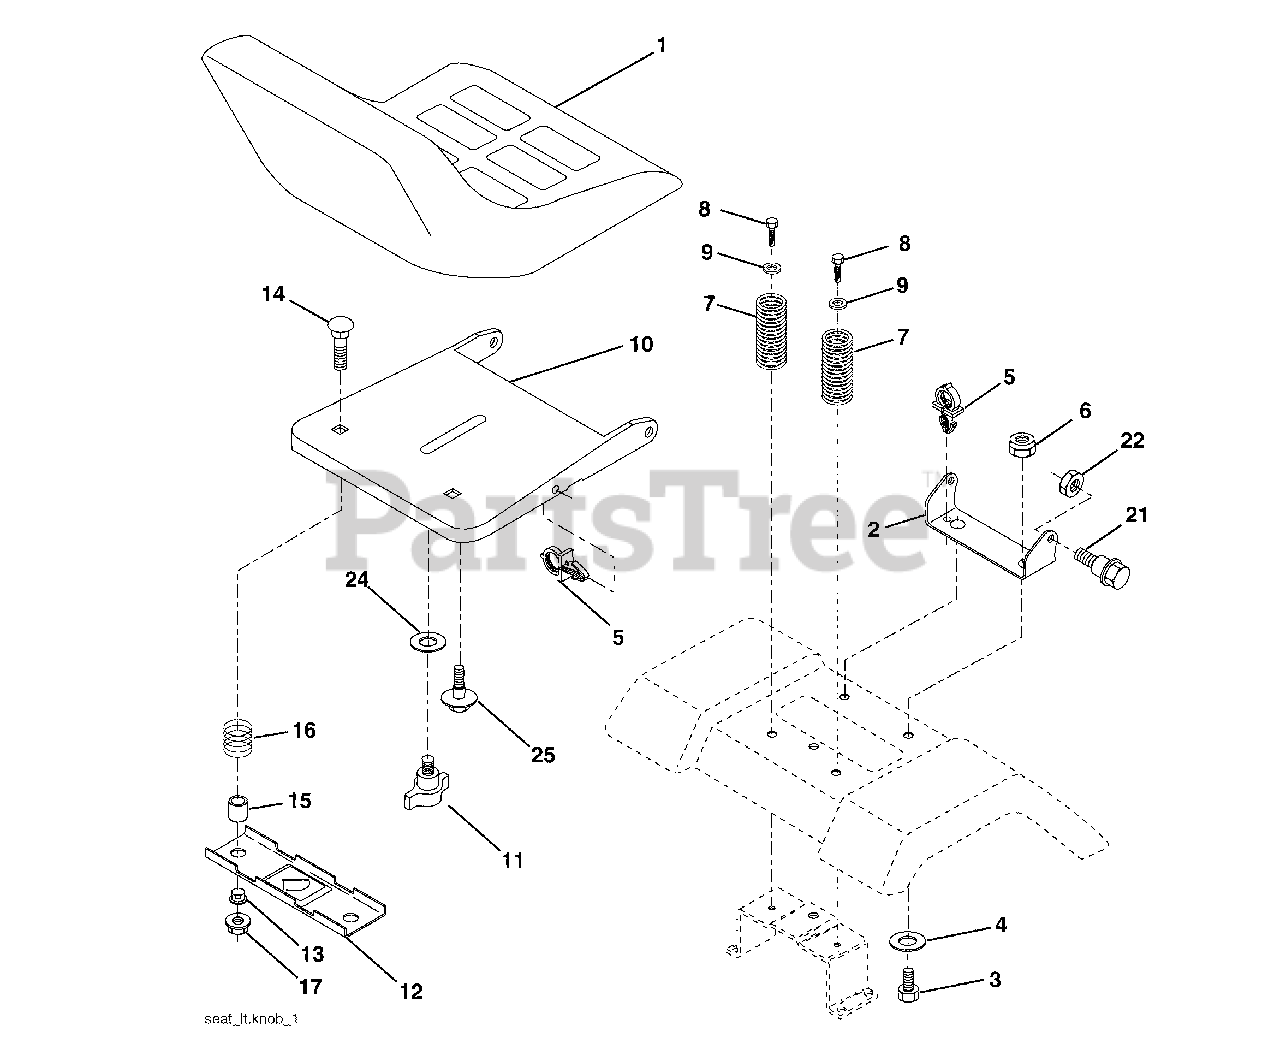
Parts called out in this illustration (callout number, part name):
1	Seat
2	Bracket Pivot Seat 8 720
3	Bolt Fin Hex 3/8-16 unc x 1
4	Washer 13/32 x 1 x 10 Ga.
5	Clip Push-In
6	Nut Hex w/Ins. 3/8-16 unc
7	Spring Seat Cprsn 2 250 Blk Zi
8	Screw 3/8-16 x 1-1/2 Smgml Tap/R Z
9	Washer 13/32 x 1 x 14 Ga.
10	Pan Seat
11	Knob Seat Adj. Wingnut
12	Bracket Mounting Switch
13	Bushing Snap Blk Nyl 50 Id
14	Bolt Rdhd Sqnk 1/4-2 x 1-1/2
16	Spring Cprsn
17	Nut Lock 1/4 Lge Flg Gr. 5 Zinc
21	Bolt Shoulder 5/16-18 unc-2a Blk DA
22	Nut Hex Lock W/Ins 5/16-18
24	Washer 17/32 x 13/16 x 12 Ga.
25	Bolt Shoulder 5/16-18 x 62
